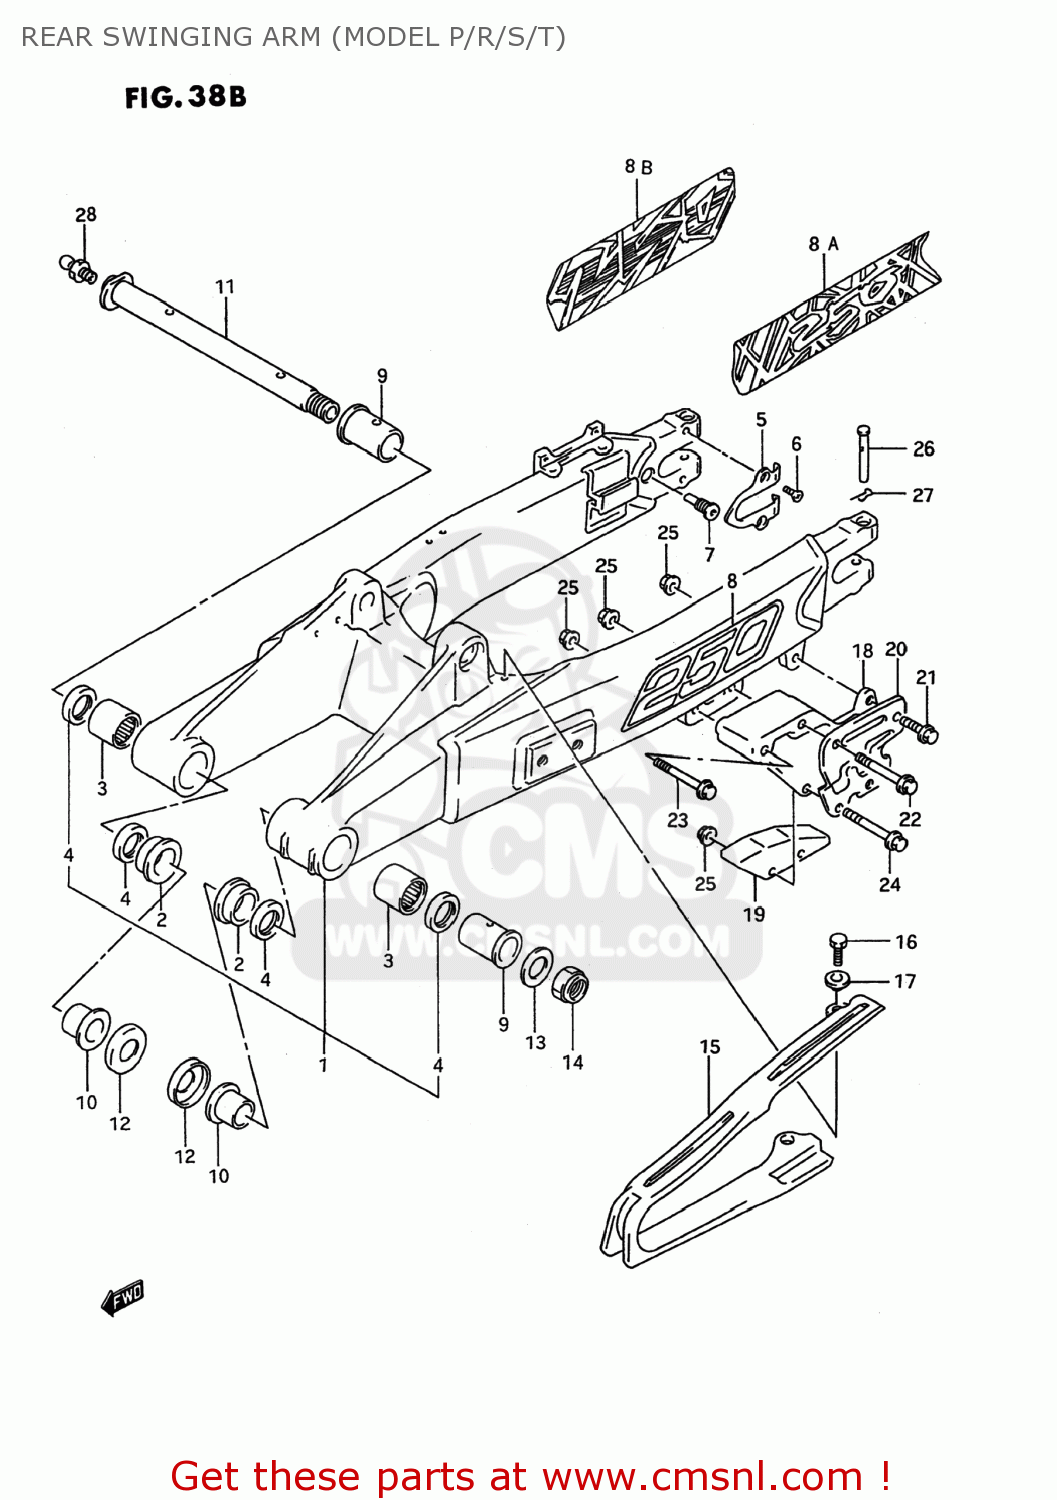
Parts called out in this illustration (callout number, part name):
1	SWING ARM ASSEMBLY,REAR
2	BUSHING,SWGARM PIVOT
3	BEARING(22X29X30)
4	SEAL,OIL(22X29X4)
5	PLATE,RR SWING ARM AXLE
6	SCREW(5X8)
7	SCREW (M10X21)
8	EMBLEM,SWINGINGARM
8A	EMBLEM (250)
8B	EMBLEM,SWING ARM,LEFT
9	SPACER,RR SWGARM PIVOT
10	SPACER,SWGARM PIVOT INNER
11	SHAFT COMP,SWING ARM PIVOT
12	COVER,SWINGINGARM PIVOT
13	WASHER
14	NUT
15	BUFFER,CHAIN TOUCH DEFENSE
16	BOLT
17	WASHER
18	GUIDE,CHAIN
19	DEFENSE,CHAIN GUIDE
20	PLATE,CHAIN GUIDE OUTER
21	BOLT
22	BOLT
23	BOLT
24	BOLT
25	NUT
26	PIN
27	CLIP
28	NIPPLE
